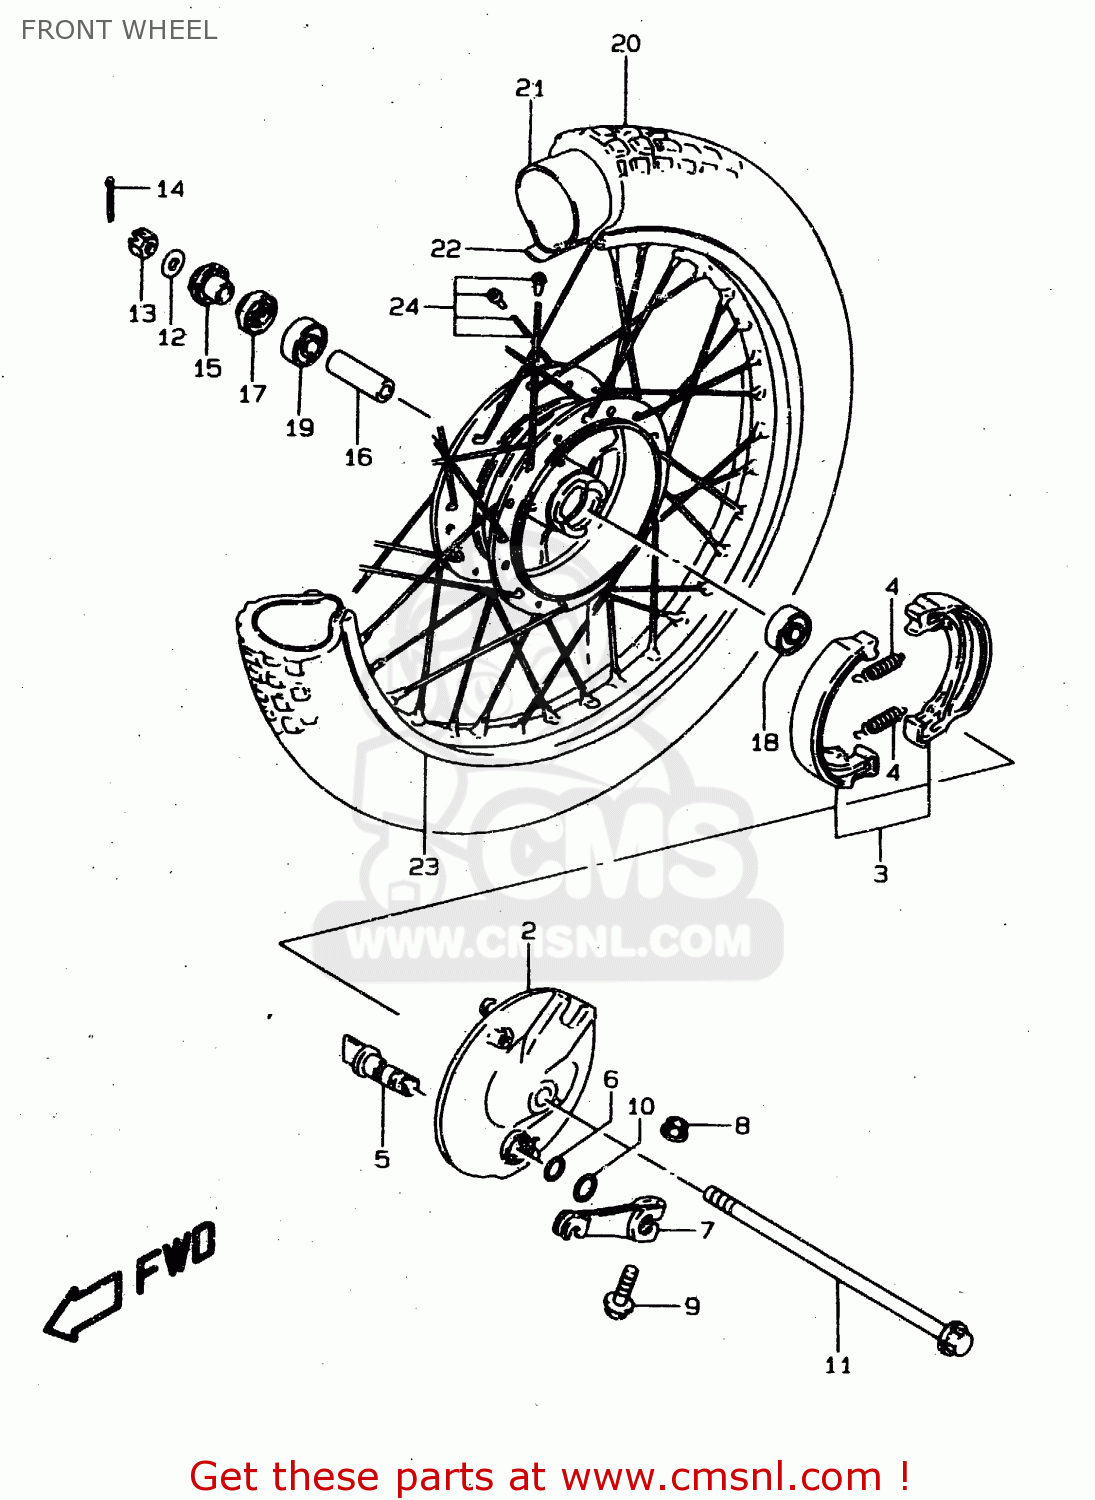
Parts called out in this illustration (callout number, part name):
1	HUB,FR
2	PANEL,FR BRAKE ANCHOR
3	SHOE SET,BRAKE (NAS)
4	SPRING(L:35.8)
5	CAM,FR BRAKE
6	O RING(D:2.5,ID:13.8)
7	LEVER,FR BRAKE CAM
8	NUT
9	BOLT
10	WASHER(14.5X22X1.6)
11	AXLE,FR
12	WASHER (10X20X2.3)
13	NUT
14	PIN 20X20
15	SPACER,FR AXLE,R
16	SPACER(10.1X16X51)
17	SEAL,OIL(15X31X5)
18	BEARING
19	BEARING
20	TIRE(2.25 14)
21	TUBE,INNER
22	PROTECTOR,INNER TUBE
23	RIM,FR WHEEL(1.40X14)
24	SPOKE SET,FR WHEEL
